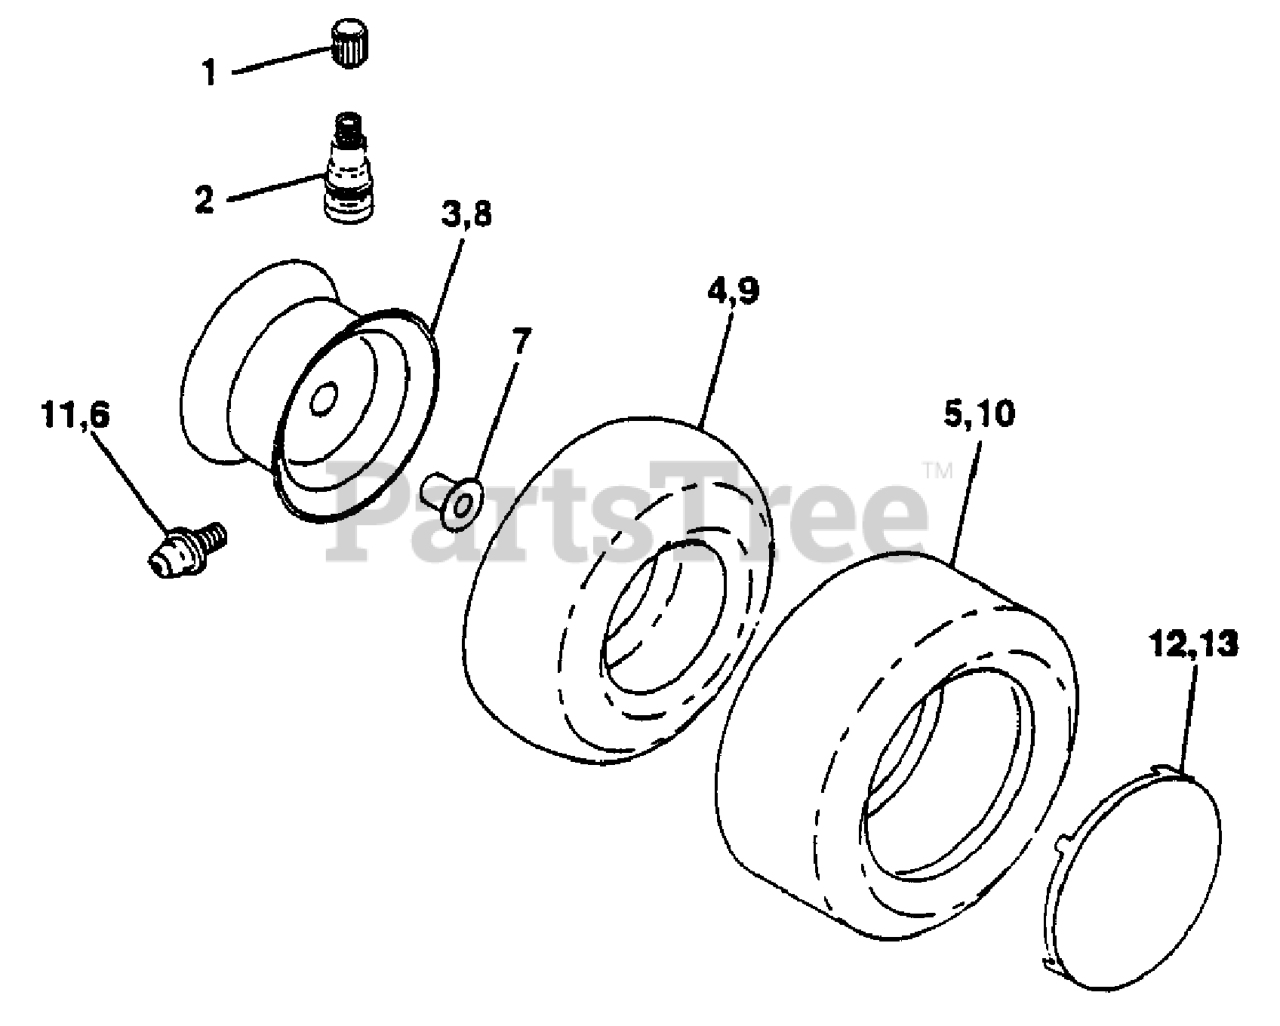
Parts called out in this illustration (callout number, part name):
2	VALVE STEM LT
3	RIM ASSY-FRONT
4	TUBE.16X6.5/7.5-8
5	TIRE HEAVY DUTY
6	FITTING LT.
7	BEARING T
8	RIM.ASM.12X7.REAR.WHITE
9	TUBE.23X9.5-12
10	TIRE HEAVY DUTY
11	ZERK FITTING M
12	CAP,HUB REAR
13	COVER,WHEEL
